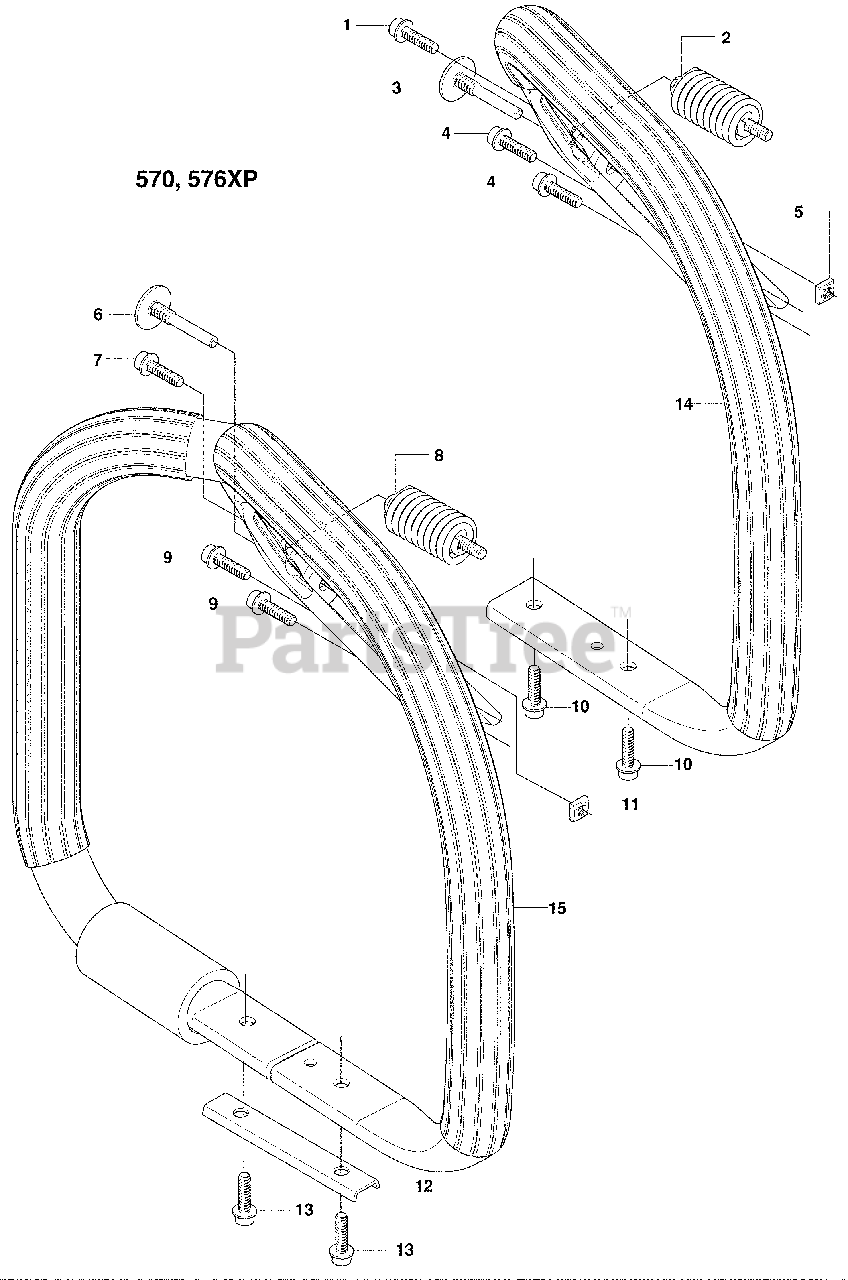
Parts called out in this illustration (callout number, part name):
2	Anti-Vibration Mount
5	Square Nut
8	Anti-Vibration Mount
11	Square Nut
14	Front Handle Assembly
15	Handle
